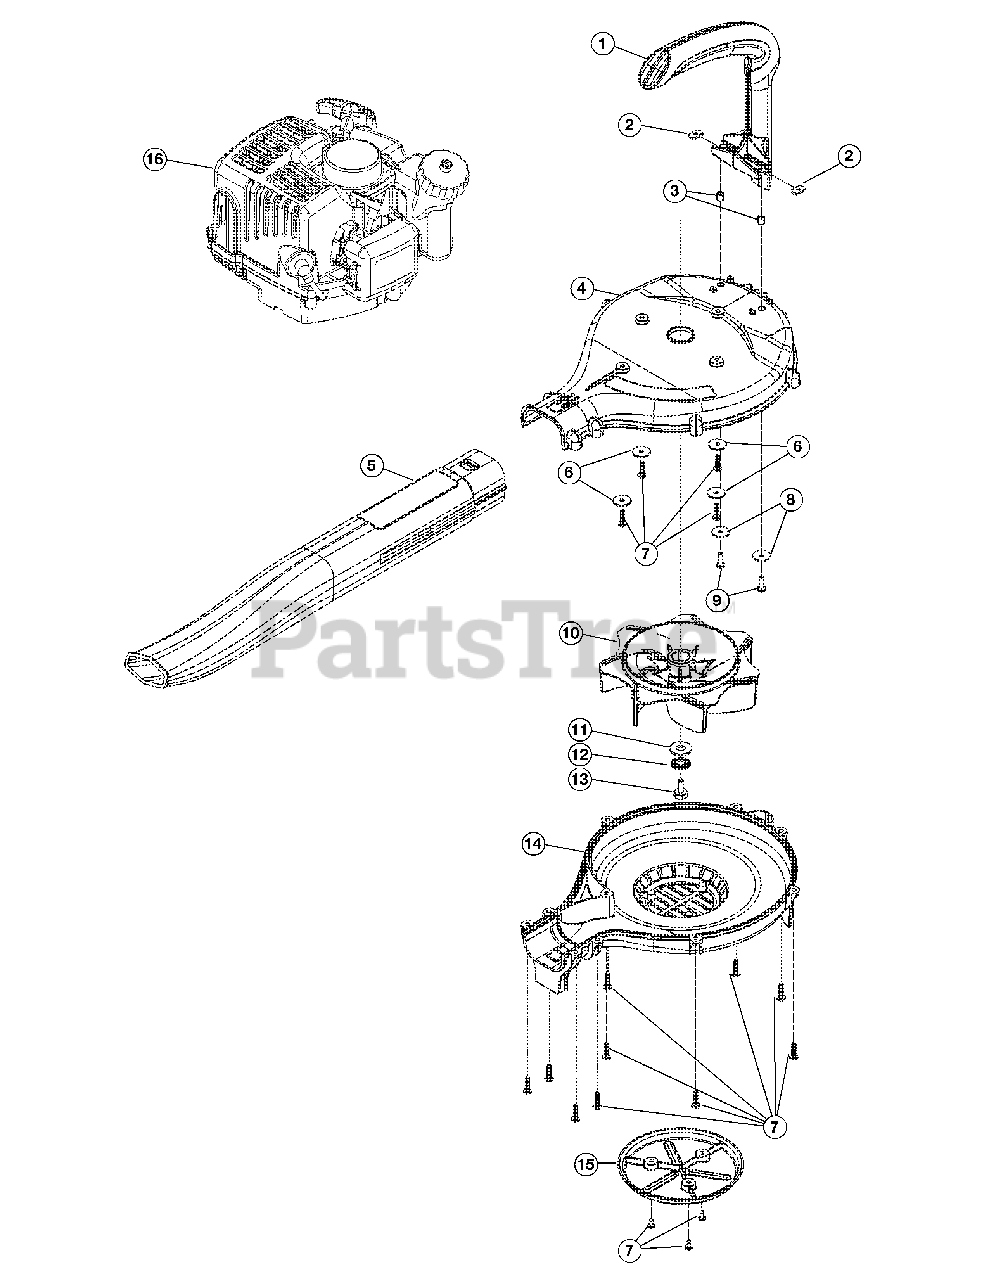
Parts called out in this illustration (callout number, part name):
1	Blower Handle
2	Weldnut
3	Spacer
4	Upper Impeller Housing
5	Blower Tube
7	Housing Screw
8	Handle Washer
9	Handle Screw
10	Impeller
11	Washer
12	Lock Washer
13	Bolt
14	Lower Impeller Housing
15	Intake Deflector
16	Engine Assembly
